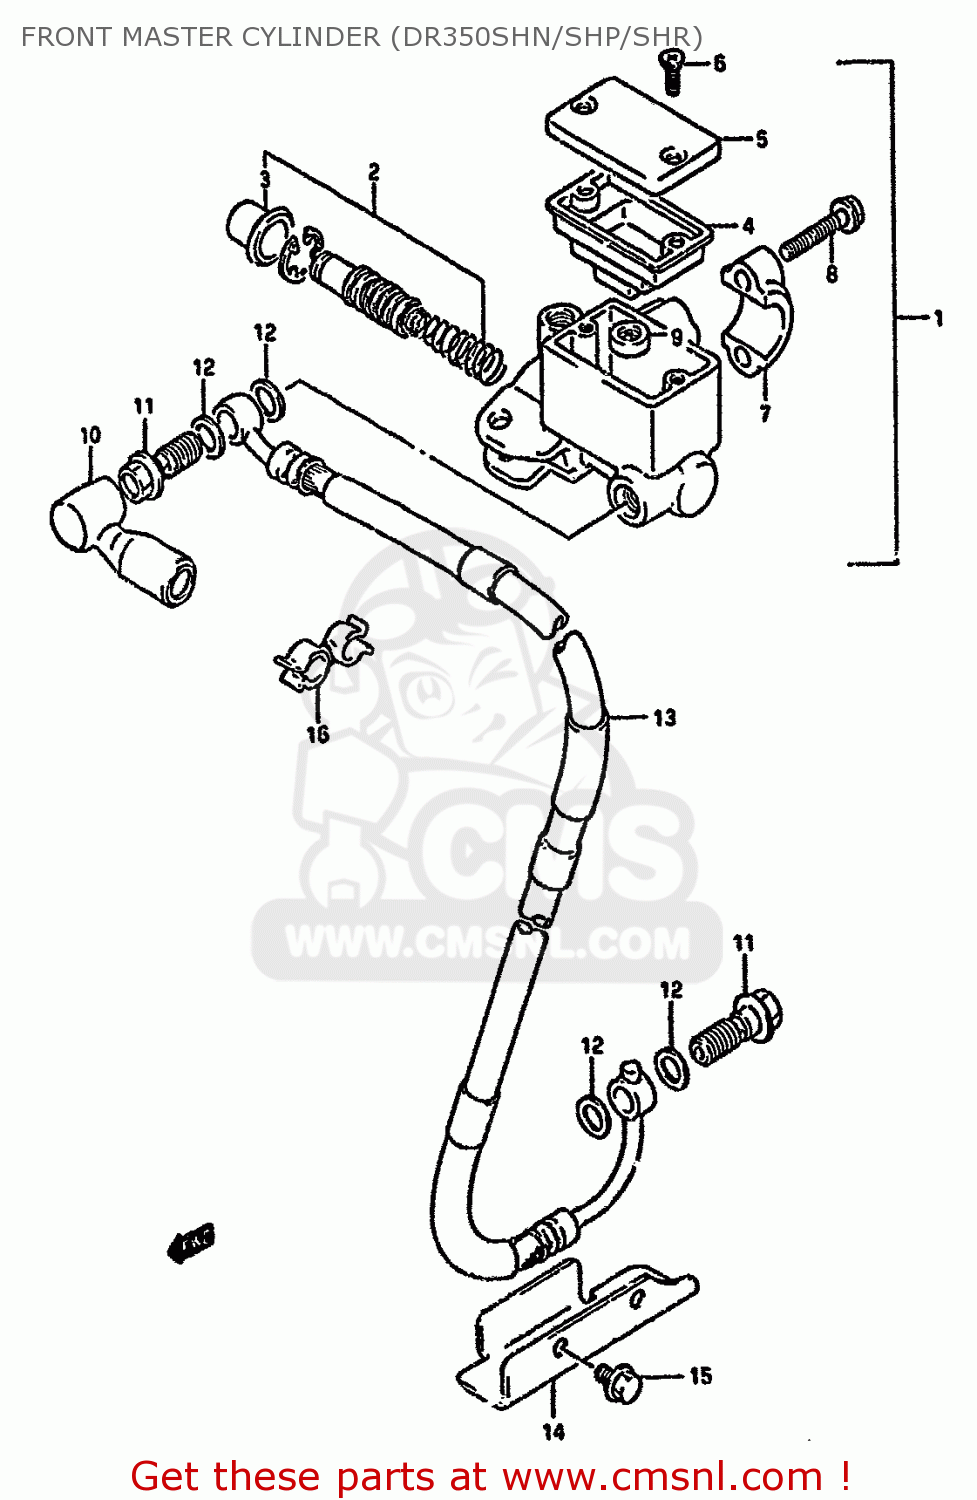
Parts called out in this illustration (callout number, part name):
1	CYLINDER ASSEMBLY,FRONT MASTER
2	PISTON/CUP SET
3	BOOT
4	DIAPHRAGM
5	CAP
6	SCREW 4X12
7	HOLDER
8	BOLT
9	SEPARATOR
10	BOOT,MASTER CYLINDER
11	BOLT UNION
12	WASHER(10X15X1.5)
13	HOSE,FRONT BRAKE
14	PROTECTOR,FRONT BRAKE HOSE
15	BOLT
16	CLIP
